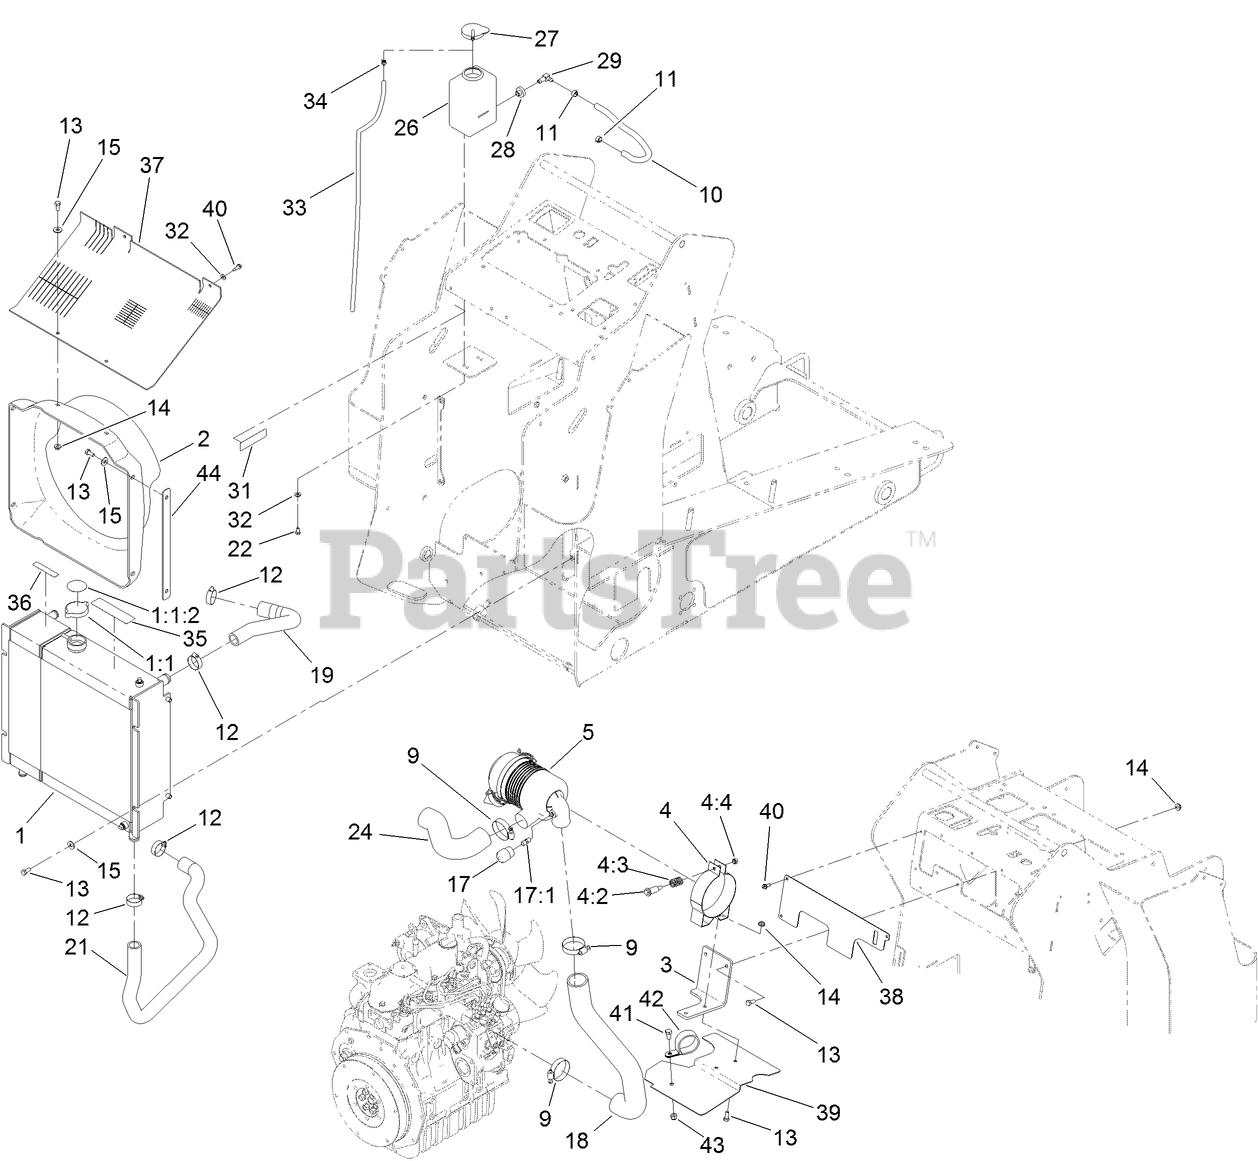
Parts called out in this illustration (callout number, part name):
1	COOLING ASM
1:1	RADIATOR CAP ASM
1:1:2	DECAL-DANGER
2	SHROUD-FAN
4	AIR CLEANER MOUNTING BAND ASM
4:3	SPRING
4:4	NUT
5	AIR CLEANER ASM
9	CLAMP-HOSE
10	HOSE-FUEL
11	CLAMP-HOSE
12	CLAMP-HOSE
13	SCREW-HH
14	NUT-HF
15	WASHER-FLAT
17	INDICATOR
17:1	ADAPTER-INDICATOR
18	HOSE-INTAKE, ENGINE
19	HOSE-RADIATOR
21	HOSE-RADIATOR, LOWER
22	SCREW-HH
24	HOSE-AIR, INLET
26	TANK-OVERFLOW
27	CAP-TANK, OVERFLOW
28	BUSHING
29	FITTING-ELBOW, 90 DEG
31	DECAL-RADIATOR FILL
32	WASHER-FLAT
33	HOSE-LP
34	CLAMP-HOSE
35	DECAL-DANGER
36	DECAL-WARNING, FAN
37	GUARD-AIR
38	COVER-AIR
39	BAFFLE-HEAT
40	SCREW-HWH, THREAD ROLL
41	SCREW-HH
42	CLAMP-R
43	NUT-LOCK, NI
44	PLATE-SHIM
